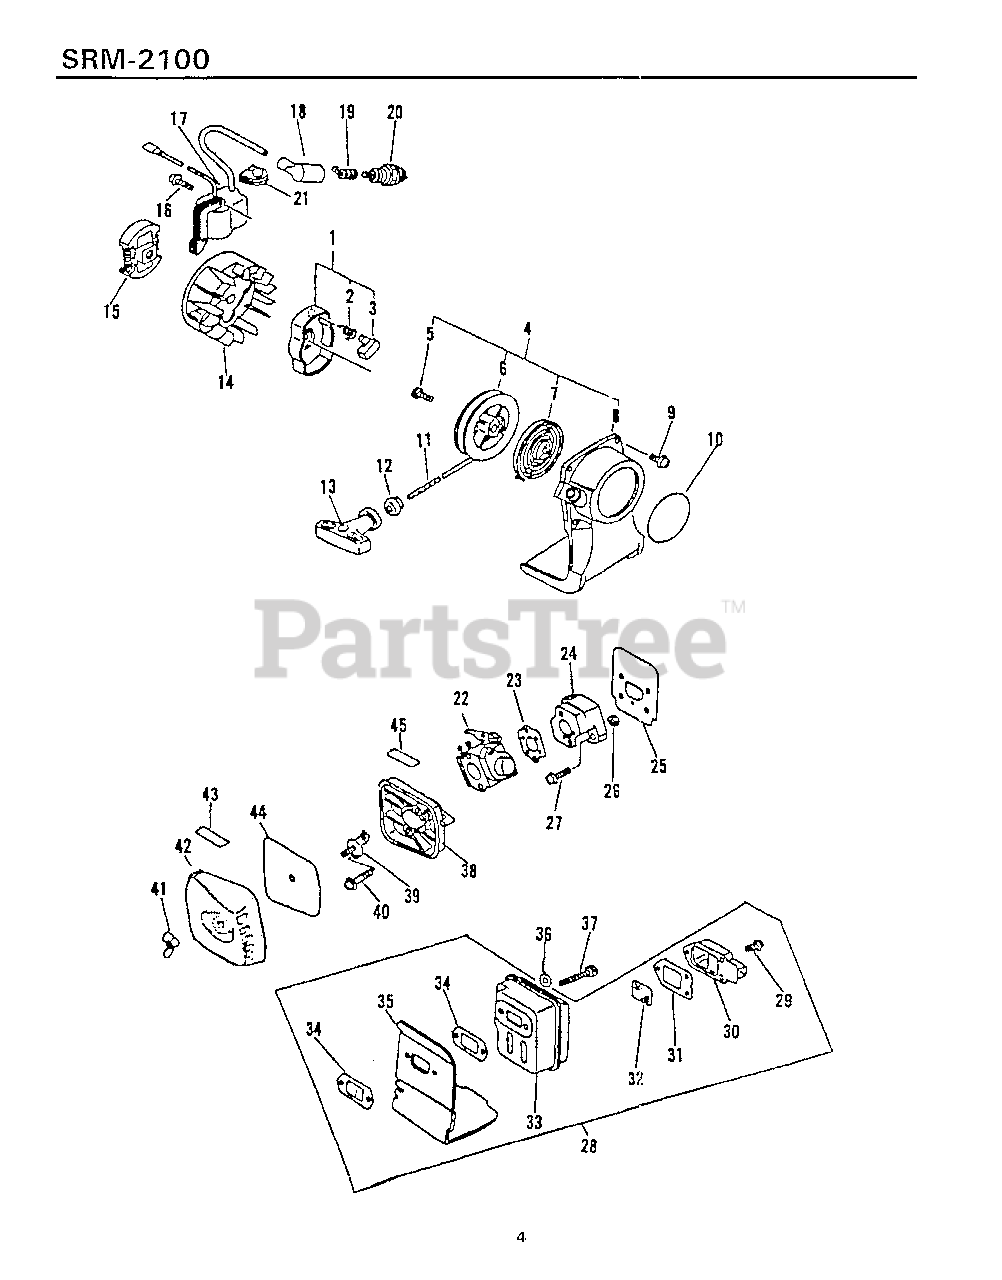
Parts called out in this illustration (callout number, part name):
1	PAWL ASSY, STARTER
2	SPRING, RETURN
3	PAWL, STARTER - BLACK
4	STARTER ASSY
5	SCREW
6	REEL, ROPE
7	SPRING, RETURN
8	CASE, RECOIL STARTER
9	BOLT 4×16
10	LABEL, ECHO
11	ROPE, STARTER
12	GUIDE, ROPE
13	GRIP, STARTER
14	FLYWHEEL
15	CLUTCH ASSY
16	SCREW 4×22
17	COIL, IGNITION
18	CAP, SPARK PLUG
19	TERMINAL, SPARK PLUG
20	SPARK PLUG - BPM7A
22	CARBURETOR - C1U-K16
23	GASKET, INTAKE
24	INSULATOR, INTAKE
25	HEAT SHIELD, INTAKE
26	NUT M5
27	SCREW 5×20
28	MUFFLER ASSY
29	SCREW 4×10
30	GUIDE, EXHAUST - INNER
31	GASKET, EXHAUST
32	SCREEN, SPARK ARRESTER
33	MUFFLER
34	GASKET, EXHAUST
35	COVER, EXHAUST
36	WASHER, FLAT 5.5×10×0.8
37	BOLT 5×55
38	AIR FILTER CASE ASSY
39	PLATE, PREVENT
40	SCREW 5×65
41	WINGNUT - 6
42	COVER, AIR FILTER
43	LABEL - TOP
44	FILTER, AIR - SINGLE LAYER
45	LABEL, CHOKE
